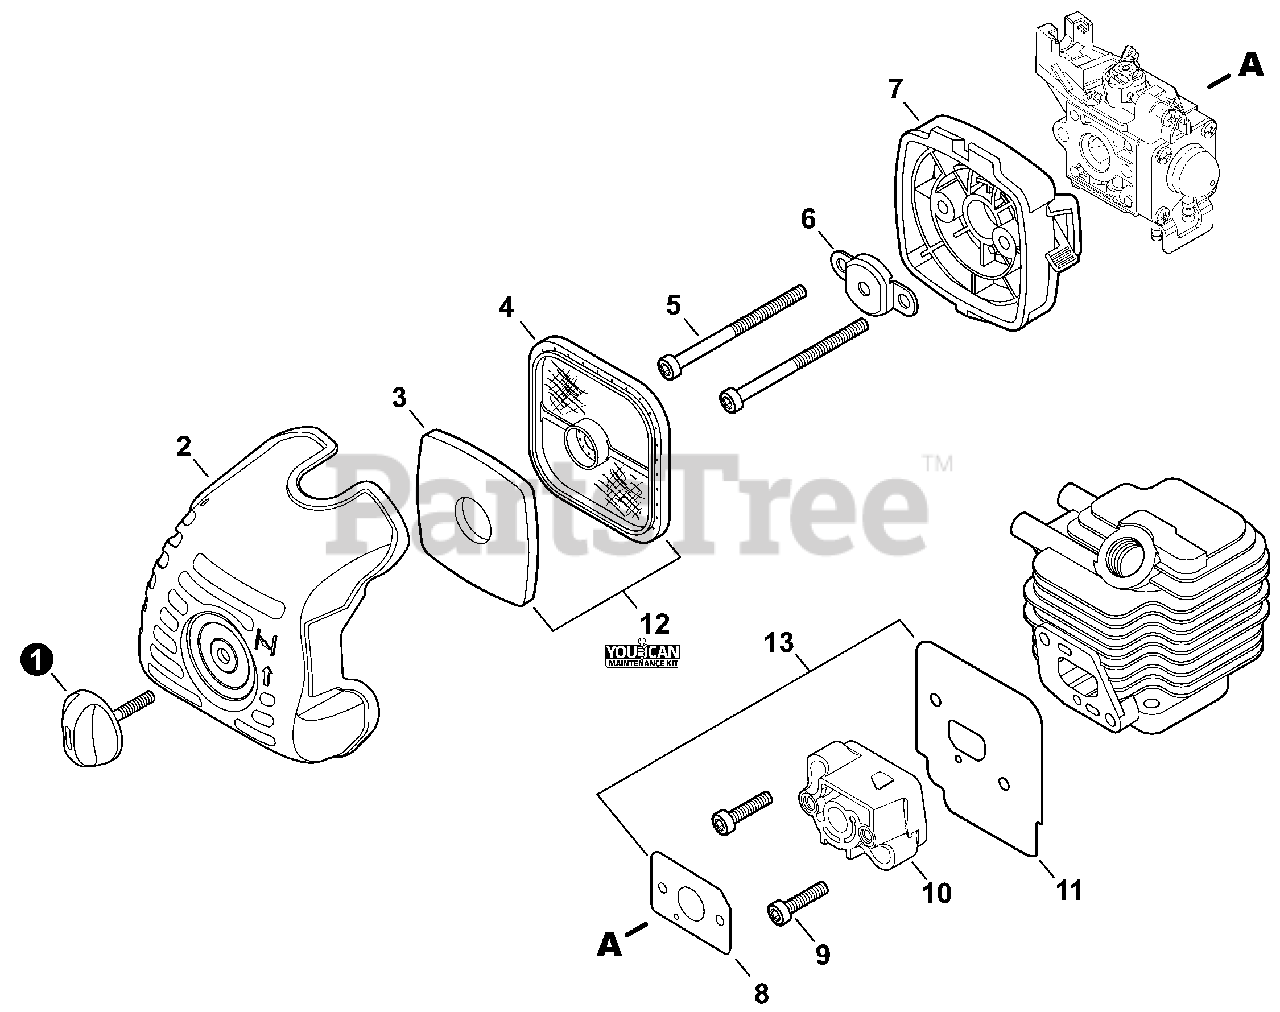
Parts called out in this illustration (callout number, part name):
1	THUMBSCREW
2	COVER, AIR FILTER
3	PRE-FILTER, FOAM
4	FILTER, AIR - DOUBLE LAYER
5	BOLT, TORX 5×55
6	PLATE, PREVENT
7	CASE, AIR FILTER
8	GASKET, INTAKE
9	BOLT, TORX 5×20
10	INSULATOR, INTAKE
11	HEAT SHIELD, INTAKE
12	TUNE-UP KIT - YOUCANT
13	GASKET KIT: ENGINE, INTAKE, EXHAUST
